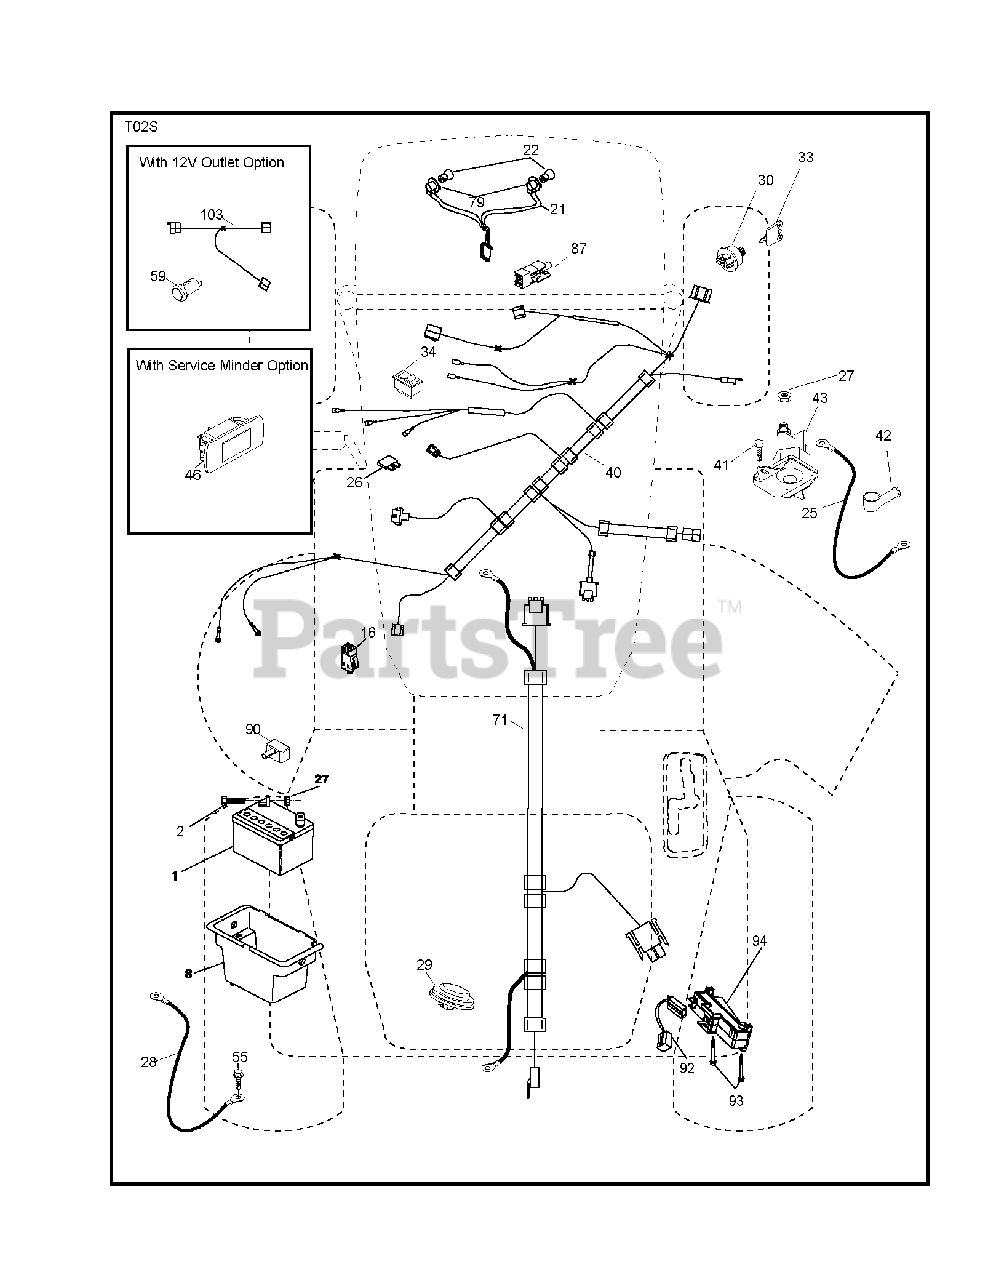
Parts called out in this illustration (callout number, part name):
1	REPL BY 532 12 38-99
2	BOLT.HEX.1/4.X.3/4.DICHROMATE
8	BOX.BATTERY.MNT.REAR.L
16	SWITCH INTERLOOK PUSH-IN
21	HARNESS ASSY LIGHT
22	LIGHTBULB
25	CABLE.STARTER.6GA.BL/RED.14.
26	FUSE 20AMP
27	NUT
28	CABLE.BLACK.18"REAR.BA
29	SWITCH.SEAT.DELTA.OPC.
30	SWITCH.IGN.DELTA.W.LGH.ROS
33	KEY.CHAIN.BLISTER.PACK.GEN.USA
34	SWITCH LT
40	HARNESS IGN. DASH
41	SCREW
42	TERMINAL COVER
43	SOLENOID.W/BRASS.PLUNGER
55	SCREW 5/16"
71	HARNESS.CHASSIS.TEX.8AWG
79	BULB HOLDER ASM.
87	SWITCH.INTRLCK.CLUTCH.
90	COVER.TERMINAL.BATTERY
92	HARNESS.PIGTAIL.CONSLE
93	SCREW.PLASTITE
94	MODULE.REVERSE.ROS
